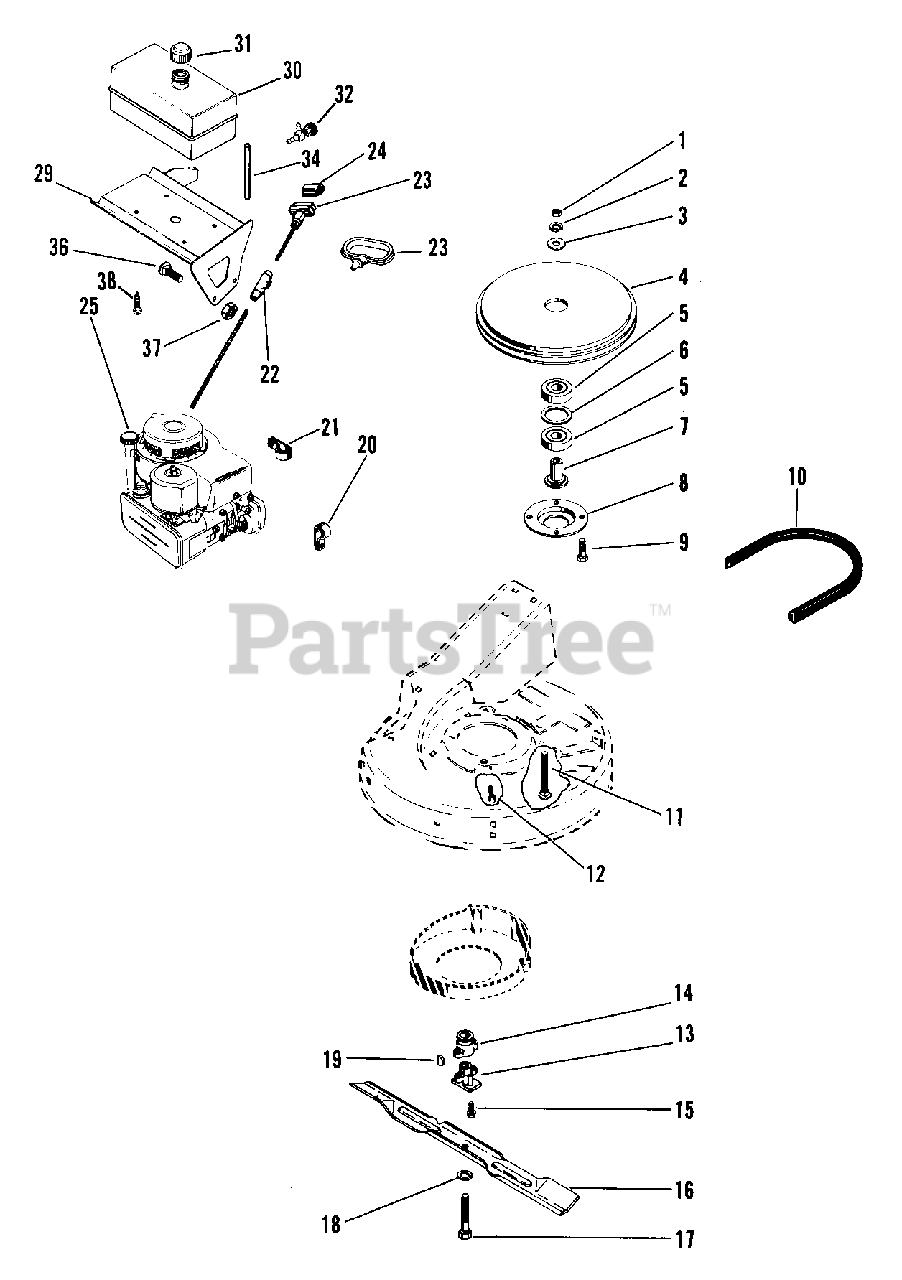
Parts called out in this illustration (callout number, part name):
1	NUT-HEX .312-18
2	WSHR-LK .312X.097 PL HVY
3	WSHR-FL-STL .328X.875X.062 PL
4	FRICTION SHEAVE
5	BRG-BALL .625X1.375X.44
6	WSHR-FL-STL 1.062X1.344X.032PL
7	SPINDLE - BEARING
8	RETAINER - BEARING
9	SCR-TAP 12-24X.50 HWH PL TR
10	V-BELT 3L 32.2
11	BLT-RDHDSQNK .31-18X1.75 PL
12	SCR-TAP .375-16X1.0 HWH PL TR
12	SCR-TAP .375-16X.75 HWH PL F
13	BLADE ADAPTER
14	TRACTION DRIVE SHEAVE
14	DRIVE PULLEY, COMMERCIAL
15	SCR-TAP 10-24X1.0 HWH PL TR
16	21" MOWER BLADE
17	BLT-HEX .38-24X2.00 PL GR5
18	WSHR-LK .375X.094 MED PL
19	KEY-WDRF .156X.625X.25 SAE 6
20	CLIP
21	CLIP
22	ROPE BULLET
23	STARTER ROPE HANDLE
23	HANDLE, RECOIL START
24	ROPE HANDLE INSERT
25	SB140-142CC SACHS
25	ENGINE, SACHS SB140
25	5HP LAUSON VERT SHFT FOR BBC
25	ENGINE,TEC 5HP VERT SHAFT BBC
25	5HP LAUSON VERT SHFT ELEC
25	ENGINE,TEC 5HP VERT SHAFT ELEC
25	5HP LAUSON VERT SHFT STD
25	ENGINE,TEC 5HP VERT SHAFT ZONE
25	ENGINE,5HP TEC BBC ELECT
25	ENGINE,BRIGGS 4 HP MAX SERIES
25	5 HP B&S IC
25	ENGINE,BRIGGS 4HP FOREIGN
25	ENGINE, BRIGGS 5 HP COMMERCIAL
26	SHIELD, MUFFLER
26	MUFFLER SHIELD
26	WSHR-FL-STL .265X.500X.087 PL
27	ENGINE BRACE
28	BLT-HEX .31-18X1.25 PL GR2
28	SCR-CAP CR W/WSHR .25-20X.50
29	BLT-XTENDED HDW/NUT .31-18 GR5
29	FUEL TANK MOUNT
30	FUEL TANK, 1 GAL
31	FUEL CAP
32	FUEL SHUT OFF VALVE
33	FUEL LINE 1/4 X 1.56"
34	FUEL LINE, 17 INCHES
35	CLAMP-FUEL LINE
36	BLT-RDHDSQNK .25-20X.50 SHT PL
37	NUT-LK-CTR .250-20 PL
38	SCR-TAP .250-14X.75 HWH PL
